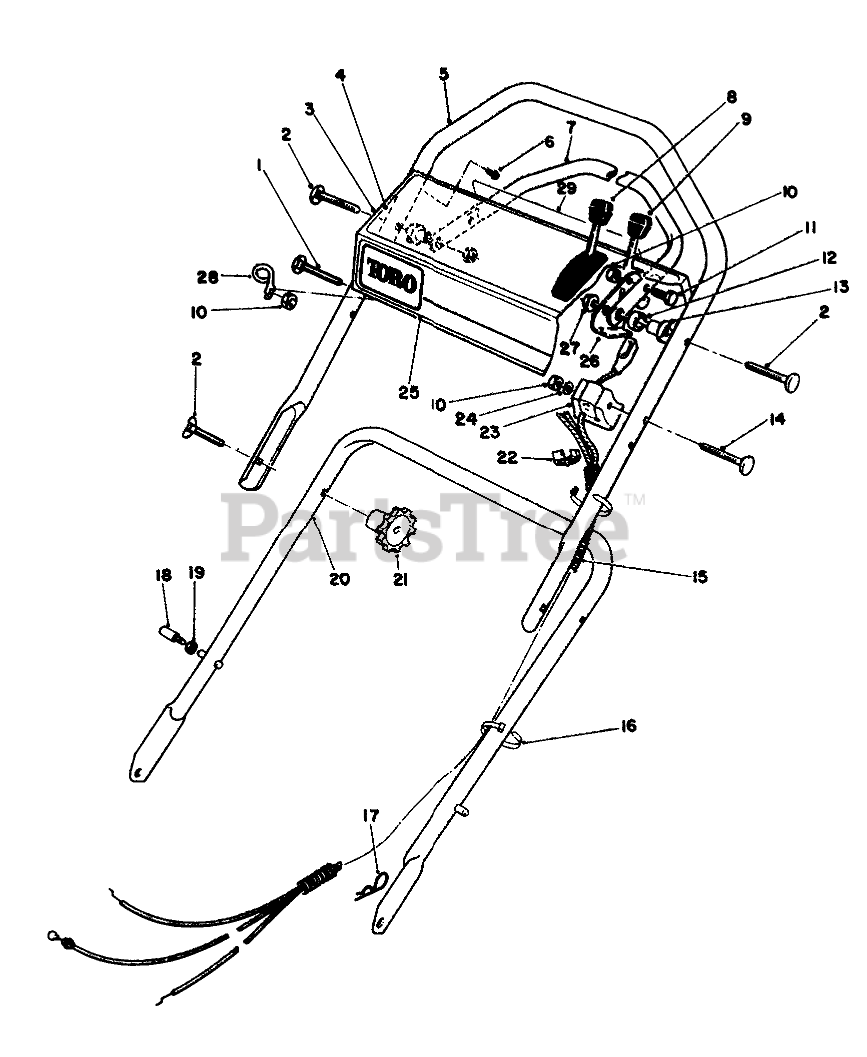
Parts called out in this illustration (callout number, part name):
1	HANDLE SCREW
2	5/16-18 X 2 HNDLE SCREW
3	Panel-Control (Incl. Ref. #4 & 29)
4	DECAL - INSTR (INT'L)
5	Handle-Upper
6	SCREW-HWHTF
7	Bar-Control
8	Control-Traction (Bend Type #3) Sheath Lg. 46")(Wire Lg. 2")
9	THROTTLE CONTROL - R&S
10	NUT-LOCK, NI
11	SCREW-HH
12	SPACER-NYLON
13	SPACER-SUPPORT
14	HANDLE SCREW
15	CONT. CABLE COVER
16	TIE-CABLE
17	PIN-COTTER, HAIR
18	HANDLE PIN
19	NUT-LOCK, NI
20	LOWER HANDLE ASM
22	FITTING-RING
23	SUPPORT-CABLE
24	WASHER-FLAT
25	DECAL - TORO PANEL
26	CONTROL LEVER
27	NUT-LOCK, NI
28	Guide
29	DECAL - PANEL, REAR
